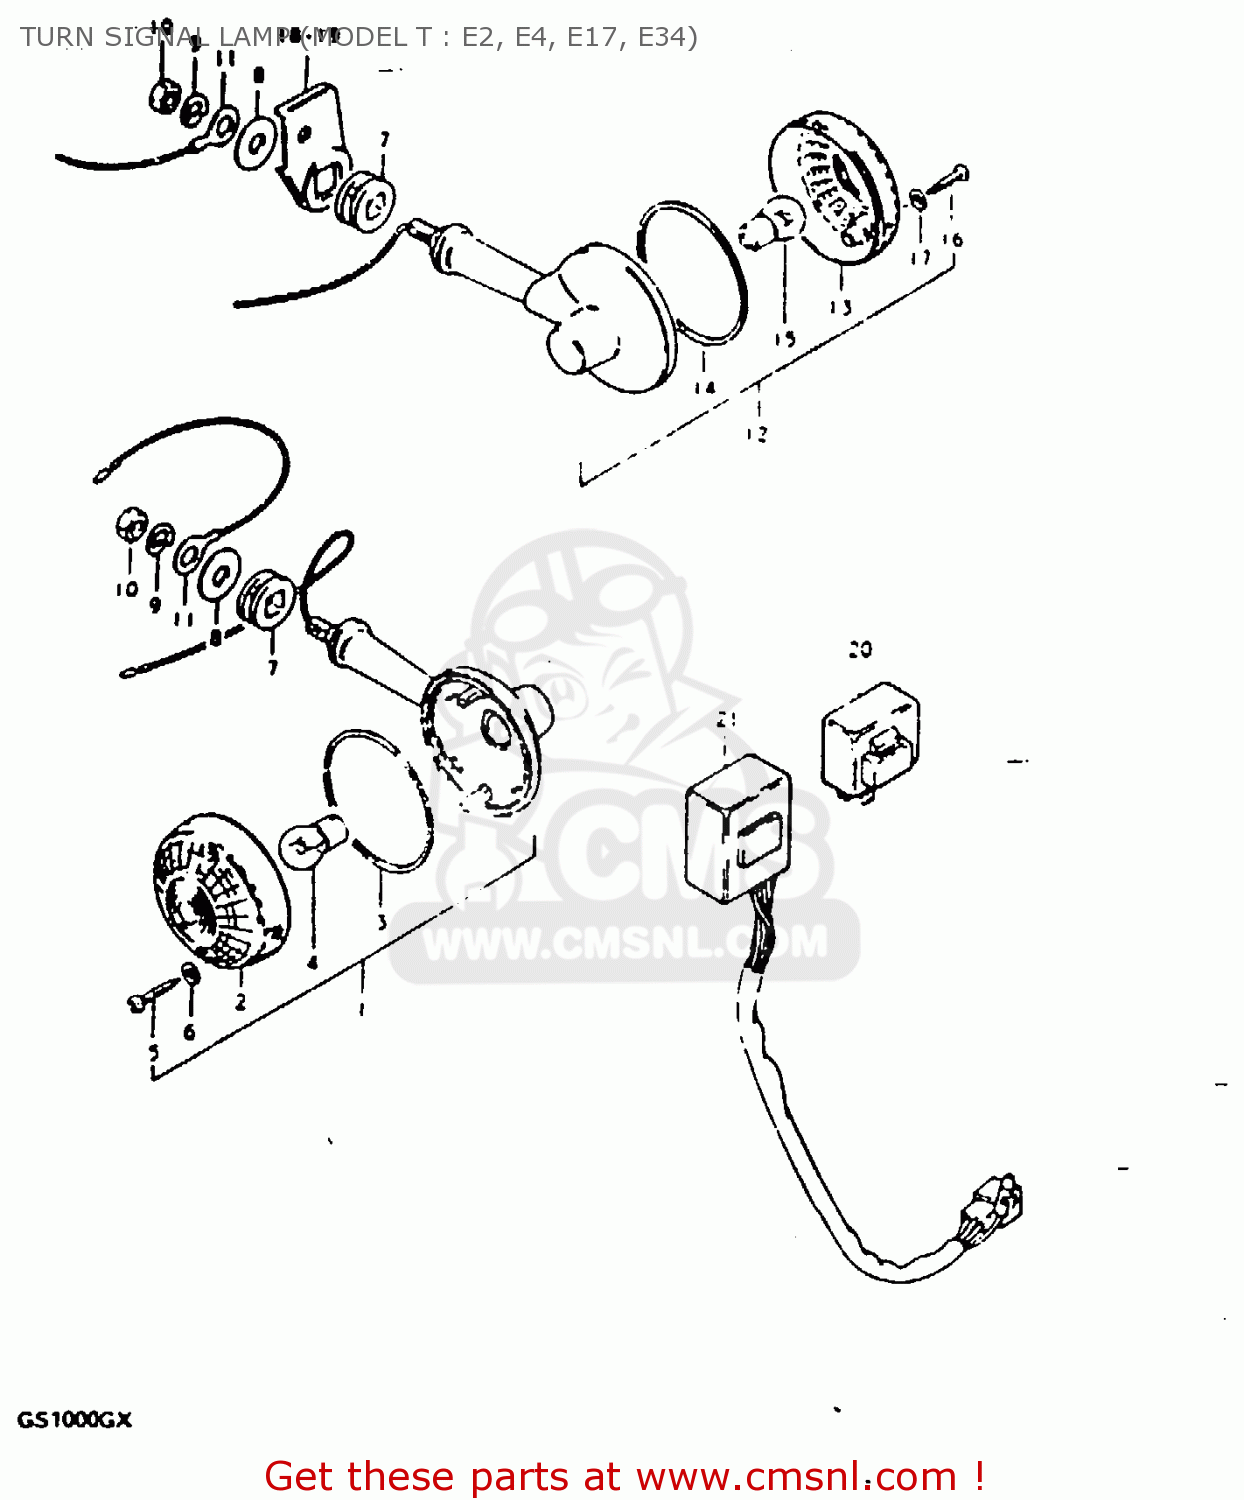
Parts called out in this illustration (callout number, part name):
1	LAMP ASSY, FRONT TURN SIGNAL
2	LENS
3	GASKET (NAS)
4	BULB 12V 21W
5	BOLT
6	GASKET (NAS)
7	CUSHION
8	WASHER
9	LOCK WASHER
10	NUT
11	LEAD WIRE,EARTH
12	LAMP ASSY, FRONT TURN SIGNAL
13	LENS
14	GASKET (NAS)
15	BULB (12V, 21W)
16	BOLT
17	GASKET (NAS)
18	BRACKET,RR TURNSIGNAL LAMP,R
19	BRACKET,RR TURNSIGNAL LAMP,L
20	RELAY ASSY,TURNSIGNAL
21	UNIT,TURN SIGNAL CONTROL
